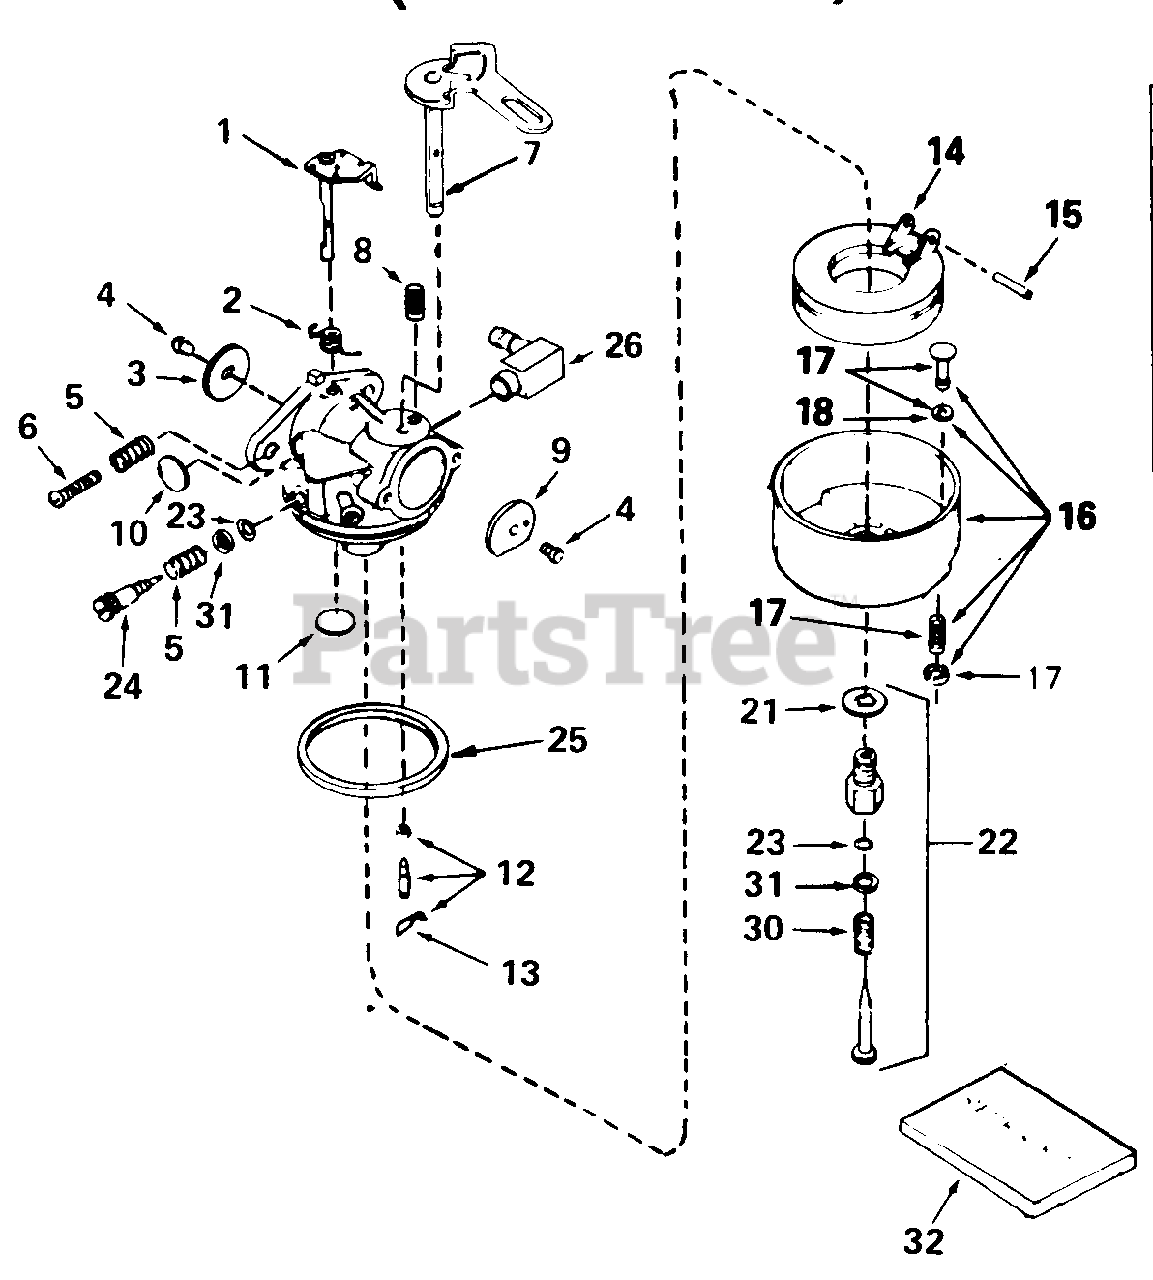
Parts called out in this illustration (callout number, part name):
1	Shaft & Lever Ass'y., Throttle
2	Spring, Throttle Return
3	Shutter, Throttle
4	Screw, 4-40 x 3/16
5	Spring, Idle Regulating Screw
6	Screw, Idle Regulating
7	Shaft & Lever Ass'y., Choke
8	Spring, Choke Stop
9	Shutter, Choke
10	Plug, Welch
11	Plug, Welch
12	Inlet Needle, Seat & Clip Ass'y.
13	Clip, Inlet Needle
14	Float, Carburetor
15	Shaft, Float
16	Bowl, Float
17	Drain Ass'y., Bowl
18	Gasket, Bowl Drain
21	Gasket, Bowl-to-Body
22	Adjustment Screw Ass'y., Main
23	"O"-Ring, Adjustment Screw
24	Screw, Idle Adjustment
25	Gasket, Bowl-to-Body
26	Fitting, Fuel Inlet
30	Spring, Main Adjustment Screw
31	Washer, Flat
32	Repair Kit
